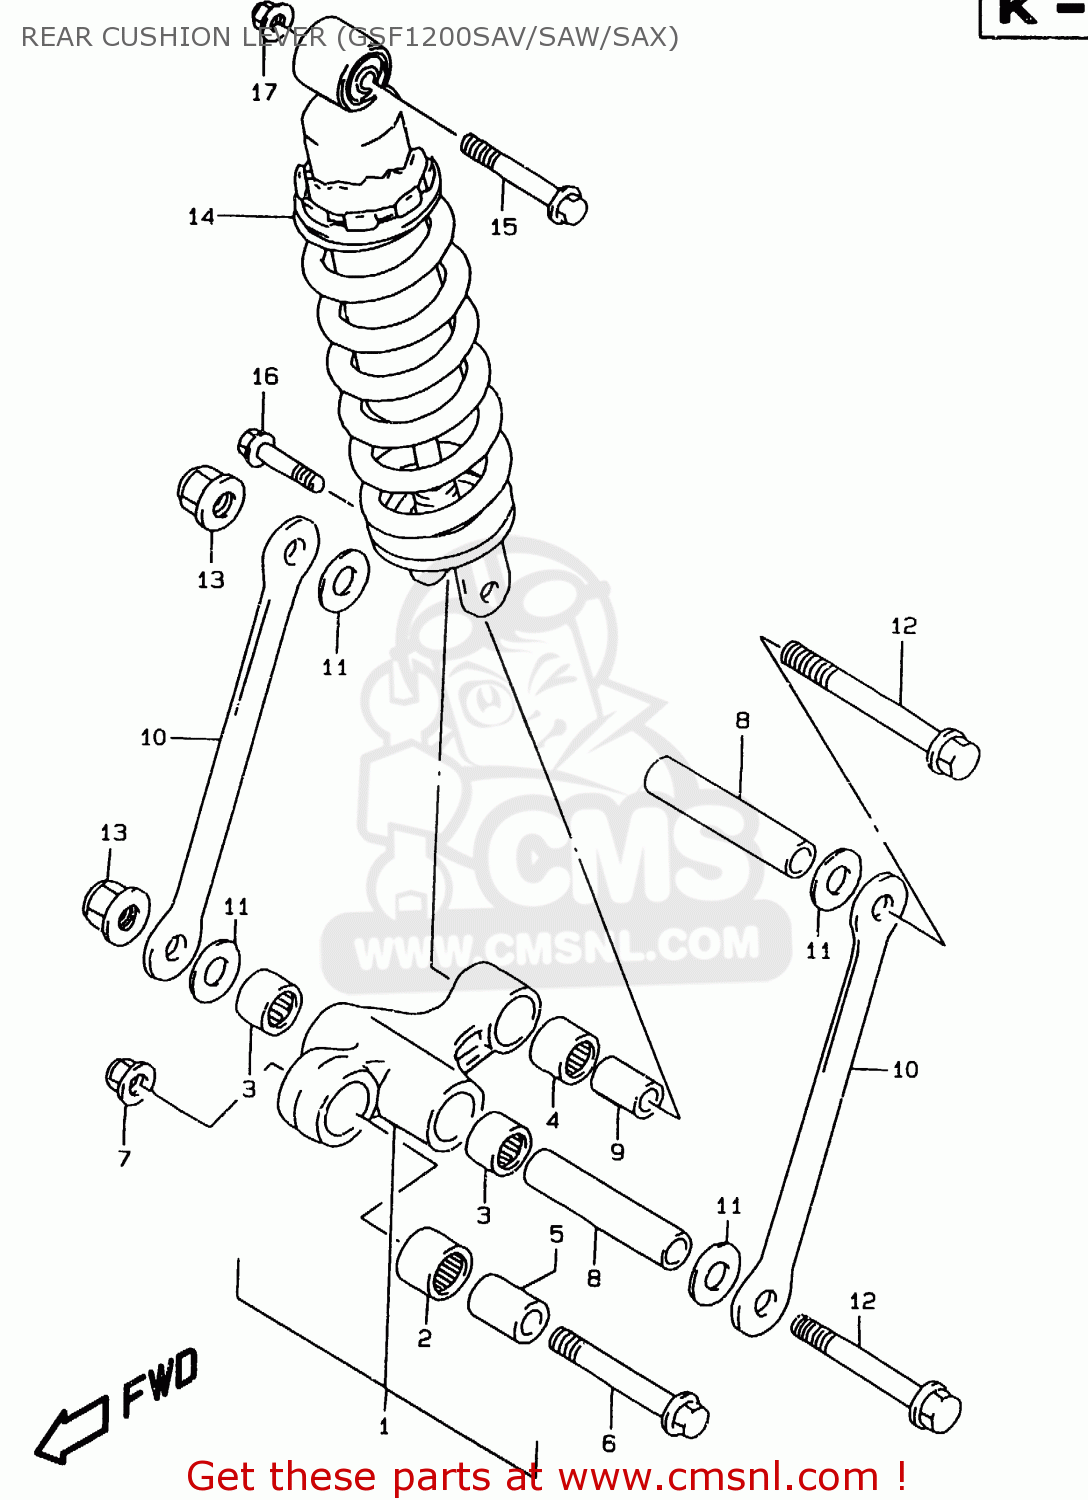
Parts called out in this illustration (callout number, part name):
1	LEVER SET,RR CUSHION
2	BEARING(20X27X26)
3	BEARING(17X24X25)
4	BEARING(17X24X26)
5	SPACER,RR CUSHION LEVER FR
6	BOLT,CUSHION LEVER FR
7	NUT 12MM
8	SPACER(12X17X85)
9	SPACER,RR CUSHION LEVER
10	ROD,RR CUSHION LEVER
11	WASHER(12X34X1)
12	BOLT(12X115)
13	NUT 12MM
14	ABSORBER ASSY, REAR SHOCK
15	BOLT(10X50)
16	BOLT(10X44)
17	NUT
